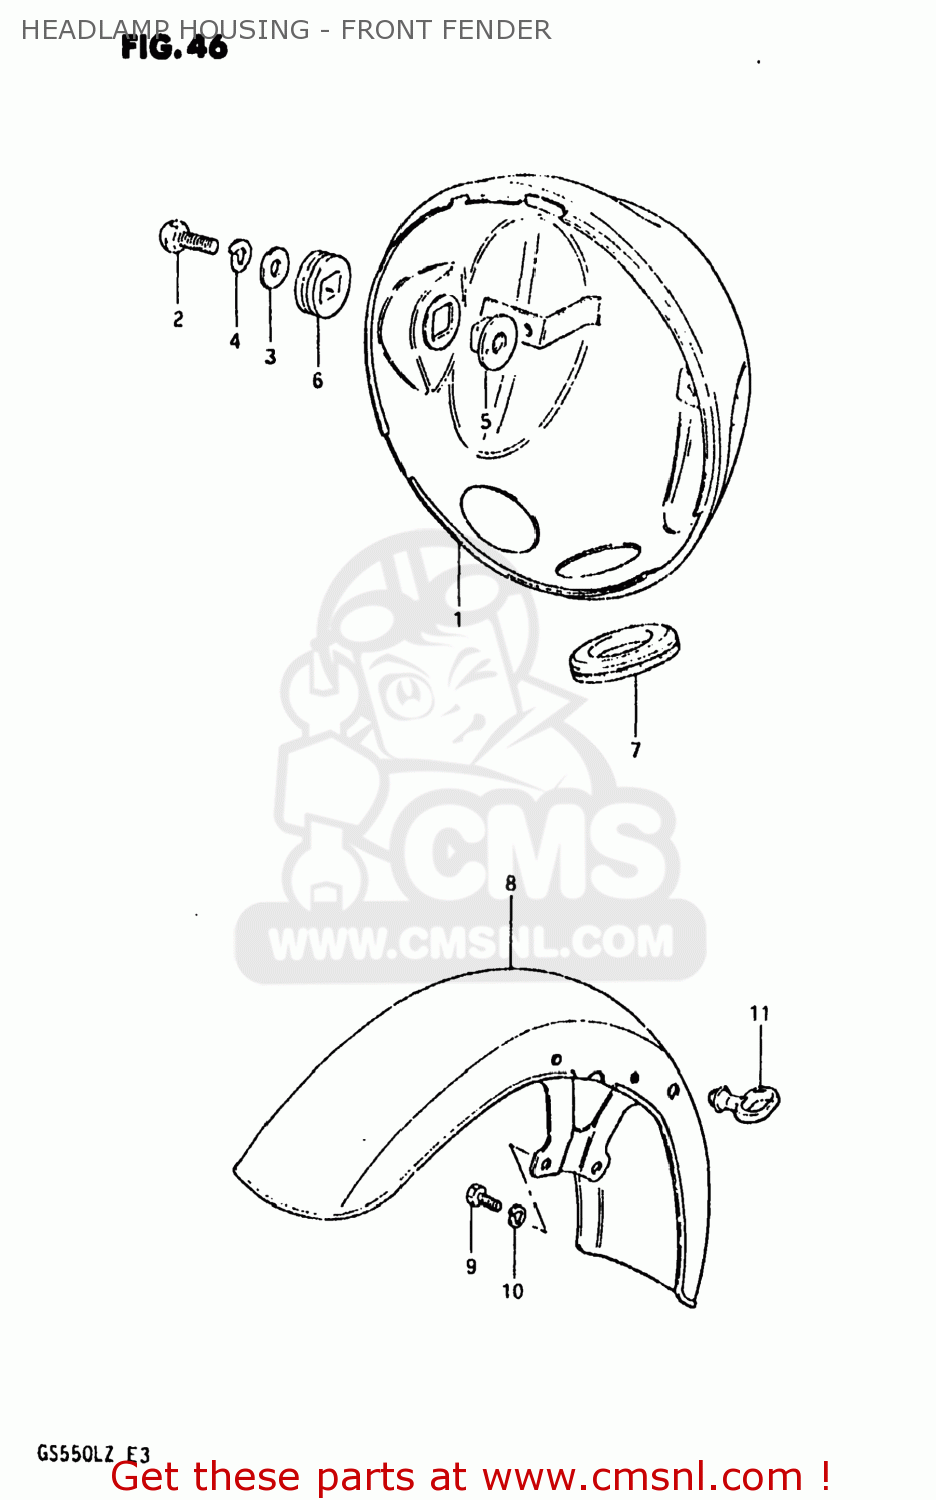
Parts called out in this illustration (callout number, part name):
1	HOUSING,HEADLAMP
2	BOLT
3	WASHER
4	LOCK WASHER
5	SPACER,HEADLAMP HOUSING
6	CUSHION,HEADLAMP HOUSING
7	GROMMET,HEADLAMP HOUSING
8	FENDER,FRONT
9	BOLT
10	LOCK WASHER
11	GUIDE,CABLE
